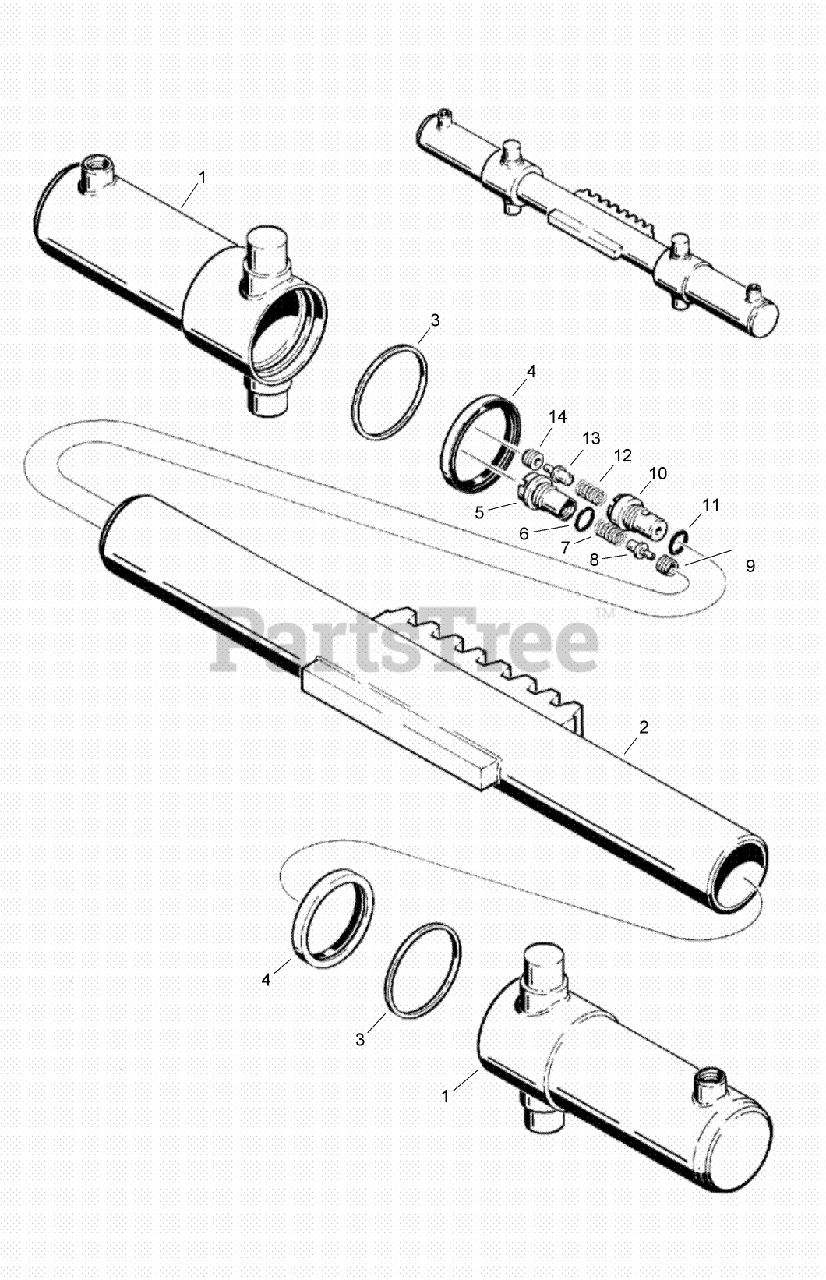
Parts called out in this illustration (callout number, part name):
1	TUBE-swing cylinder, D100 backhoe
2	ROD-piston, swing cylinder, D100 backhoe
3	Seal-Lip
4	SEAL-dust, tube to piston rod
5	BODY-relief valve
6	O-RING-3/4 ID x 3/32 inch wide
7	SPRING-relief valve
8	POPPET-relief valve
9	SEAT-relief valve
10	BODY-relief valve
11	O-RING-3/4 ID x 3/32 inch wide
12	SPRING-relief valve
13	POPPET-relief valve
14	SEAT-relief valve
